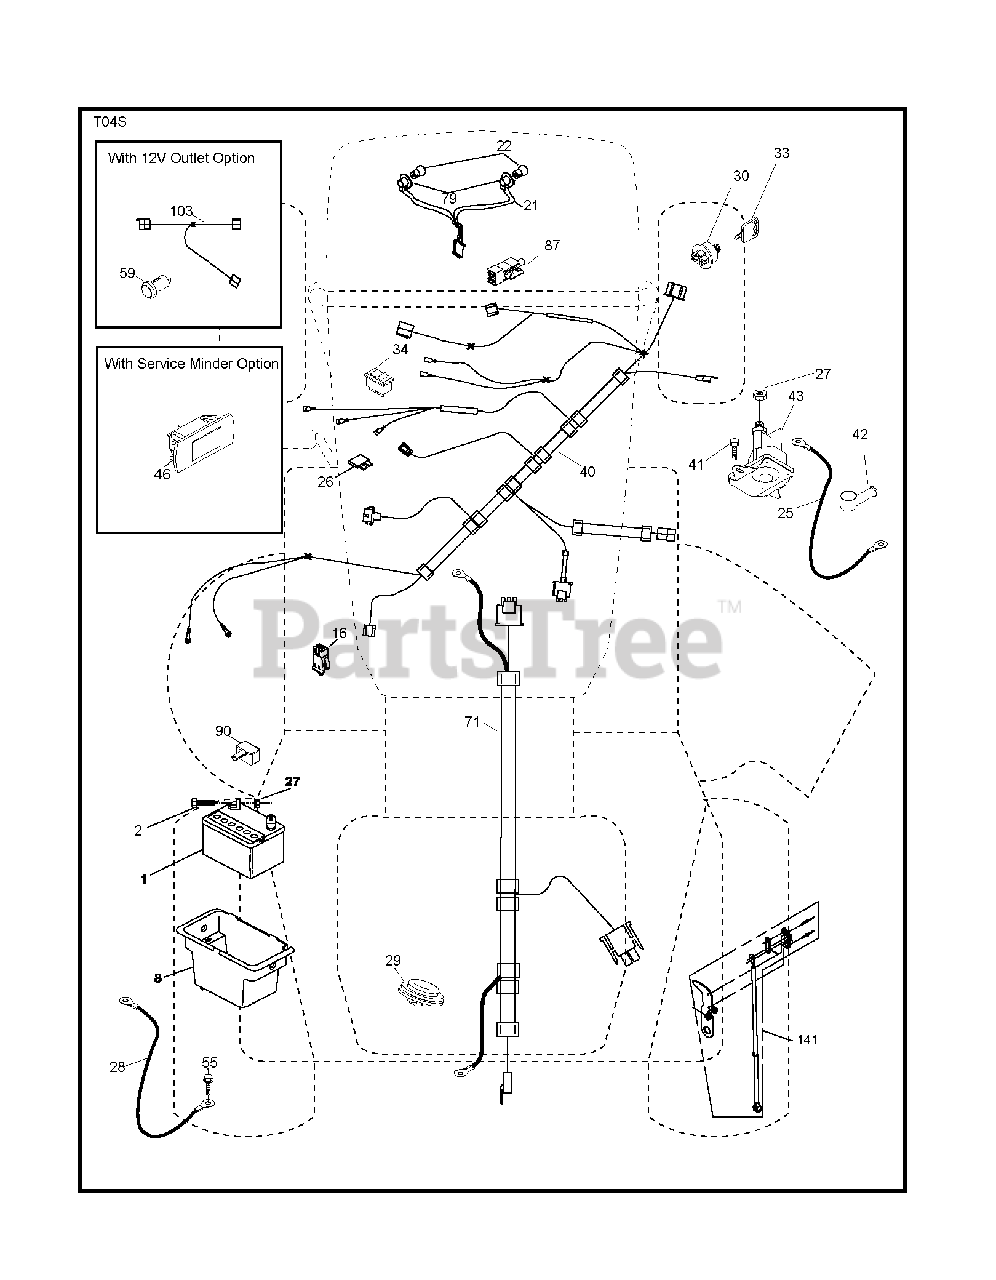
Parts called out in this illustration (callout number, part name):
1	REPL BY 532 12 38-99
2	BOLT.HEX.1/4.X.3/4.DICHROMATE
8	BOX.BATTERY.MNT.REAR.L
16	SWITCH INTERLOOK PUSH-IN
21	HARNESS.LIGHT W/4152J BULBS
25	CABLE.STARTER.6GA.BL/RED.14.
26	FUSE 20AMP
27	NUT
28	CABLE.BLACK.18"REAR.BA
29	SWITCH.SEAT.DELTA.OPC.
30	SWITCH.IGN.DELTA.W.LGH.ROS
33	KEY.CHAIN.BLISTER.PACK.GEN.USA
40	HARNESS IGN. DASH
41	SCREW
42	TERMINAL COVER
43	SOLENOID.W/BRASS.PLUNGER
46	RP GUAGE.SRVCMNDR.HRMTR.
55	SCREW 5/16"
71	HARNESS.CHASSIS.TEX.8AWG
79	BULB HOLDER ASM.
87	SWITCH.INTRLCK.CLUTCH.
90	COVER.TERMINAL.BATTERY
141	KIT T2.ROS 71677
